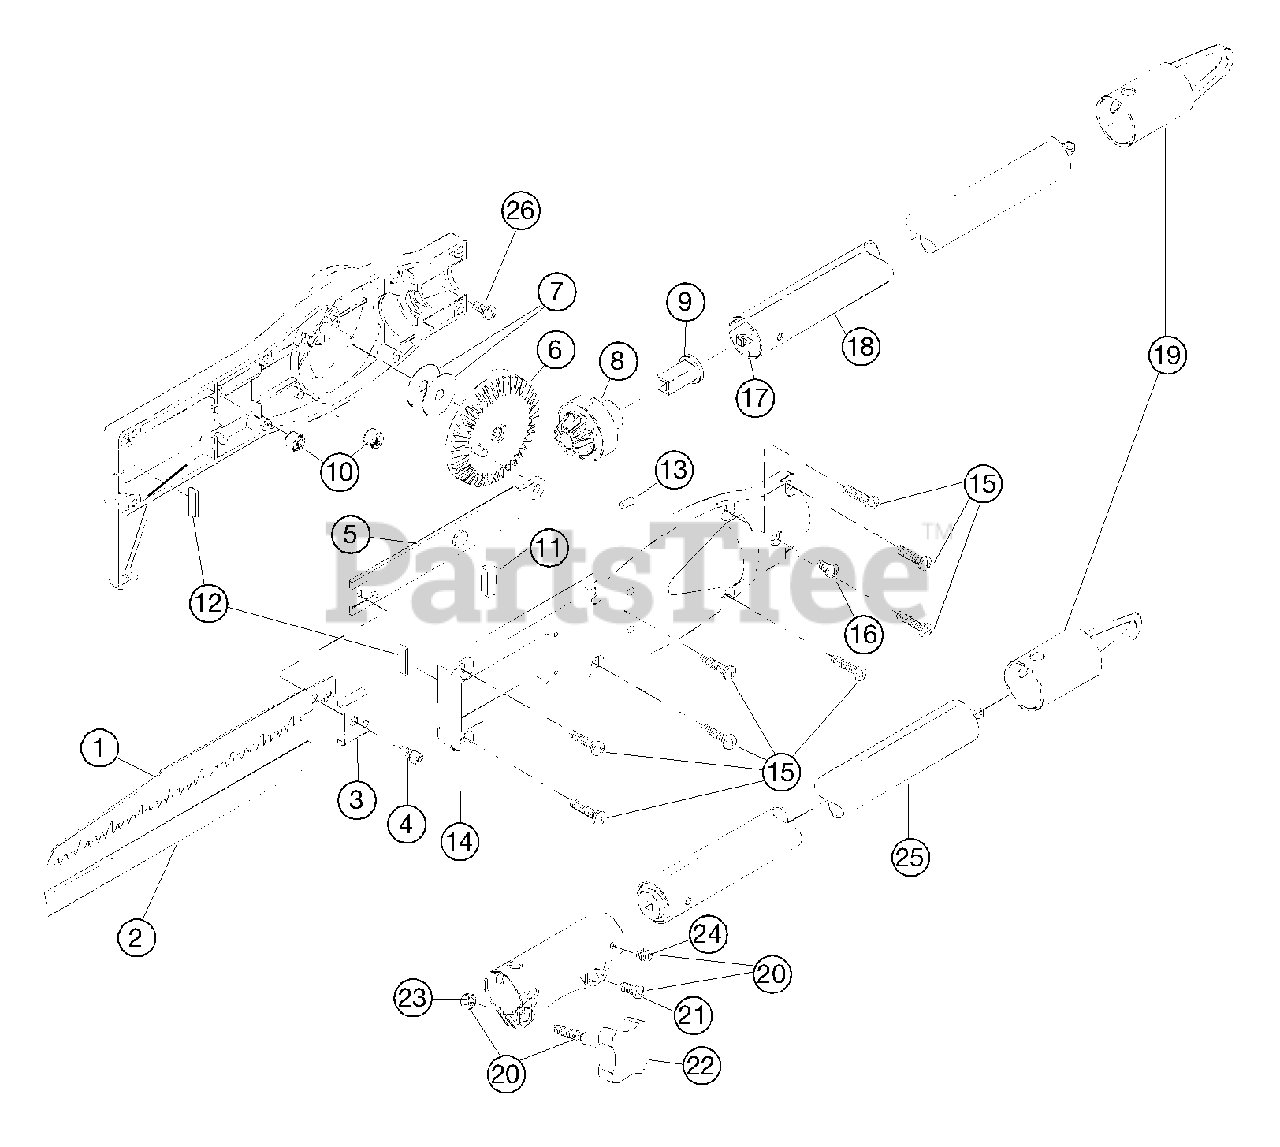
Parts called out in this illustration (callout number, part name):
1	Blade (2 pack)
2	Blade Cover
3	Blade Clamp
4	Blade Clamp Screw and Washer Assembly
5	Arbor Assembly
6	Bevel Gear
8	Pinion Bevel Gear
9	Insulator
10	Slide Bushing
11	Felt Seal
12	Slider (2-pack)
13	Rubber Plug
14	Housing set
15	Housing Screw (8 required)
16	Anti-Rotation Screw
17	Drive Shaft Assembly
18	Drive Shaft Housing Assembly
19	Hanger
20	Coupler
22	Adjustment Knob
23	Knob Retaining Nut
25	Extension Boom and Flex Shaft Assembly
26	Anti-Rotation Screw
